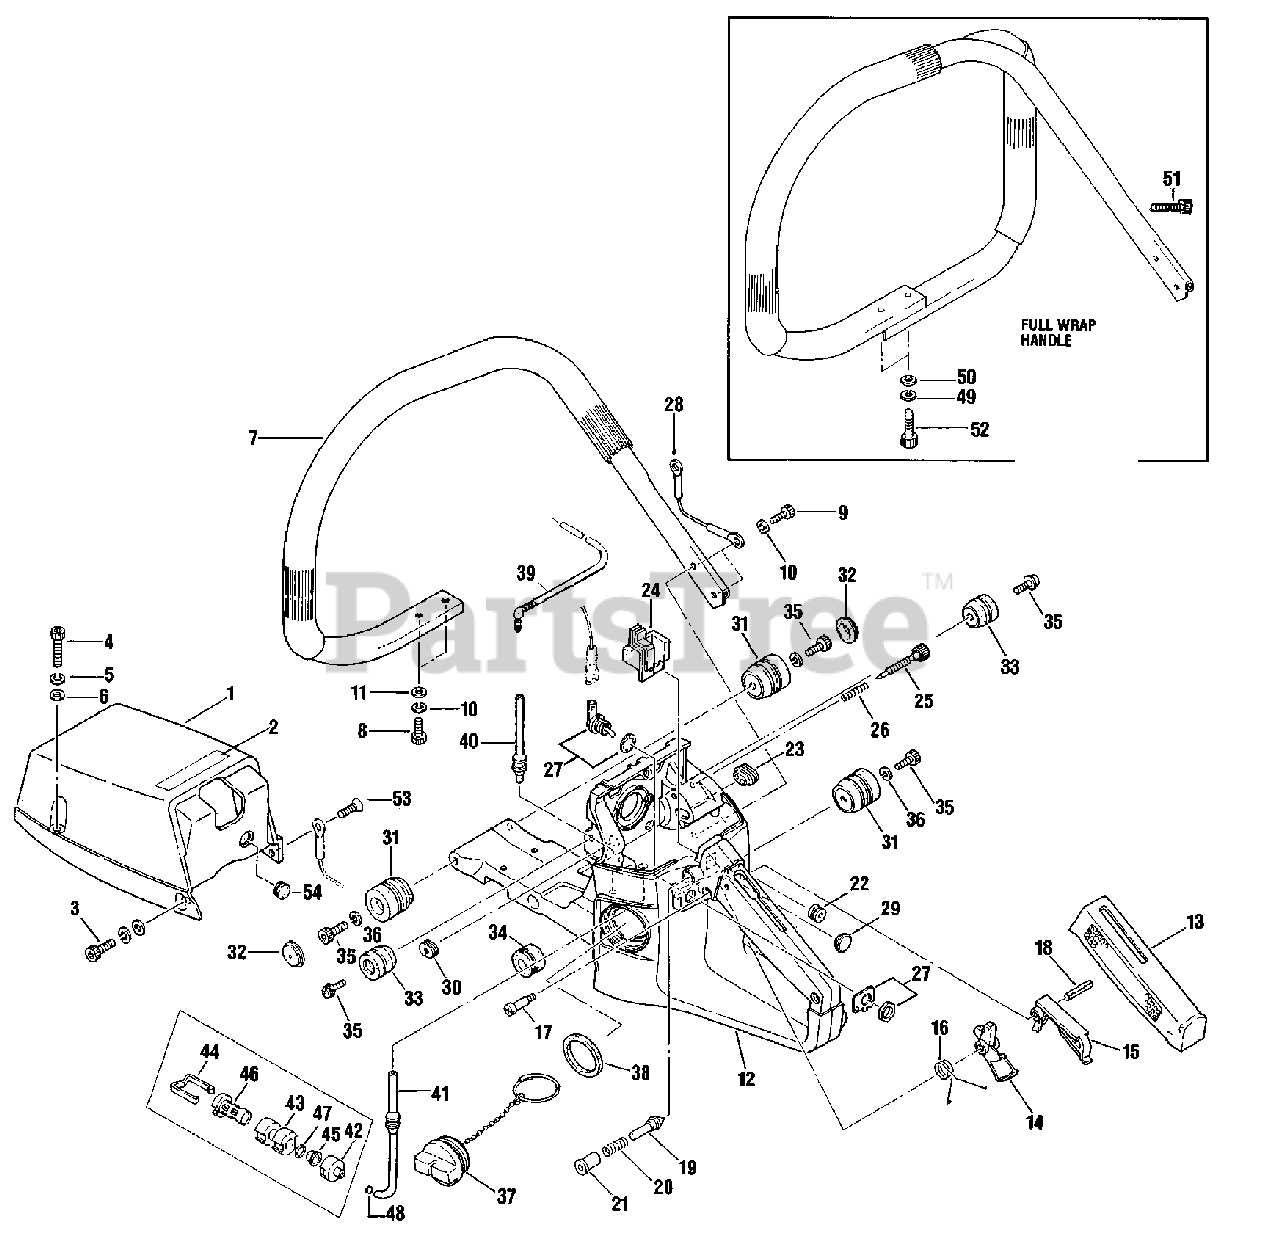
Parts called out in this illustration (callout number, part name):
1	COVER, ENGINE
2	LABEL - CAUTION
3	SCREW - 5X15
4	SCREW - 5X25
5	LOCKWASHER - 5
6	WASHER - 5
7	HANDLE - FRONT
8	SCREW - 5X15
9	SCREW - 5X18
10	LOCKWASHER - 5
11	WASHER - 5
12	HANDLE ASSY - REAR
13	GRIP, HANDLE
14	TRIGGER, THROTTLE
15	LEVER, LOCK
16	LEVER, SPRING
17	BOLT
18	PIN
19	PIN - LOCKING
21	KNOB, STOPPER
22	GROMMET
24	GROMMET
25	SCREW, ADJUST
26	SPRING, ADJUST
27	IGNITION SWITCH ASSY
28	LEAD - GROUND
29	PLUG
30	GROMMET
31	CUSHION - 26
32	PLUG
33	CUSHION - 22
34	SUPPORT
35	BOLT, LIMITER
36	LOCKWASHER - 5
37	CAP, FUEL
38	GASKET
39	VENT, FUEL TANK
40	TUBE
41	PIPE
42	WEIGHT, FUEL FILTER
43	FILTER, FUEL
44	CLIP, FILTER
45	SCREEN, FILTER
46	CASE, FILTER
47	RING, RETAINING
48	RING, RETAINING - 6
49	LOCKWASHER - 5
50	WASHER - 5
51	BOLT
52	SCREW - 5X30
53	SCREW - 5X12
54	PLUG, BRACKET
